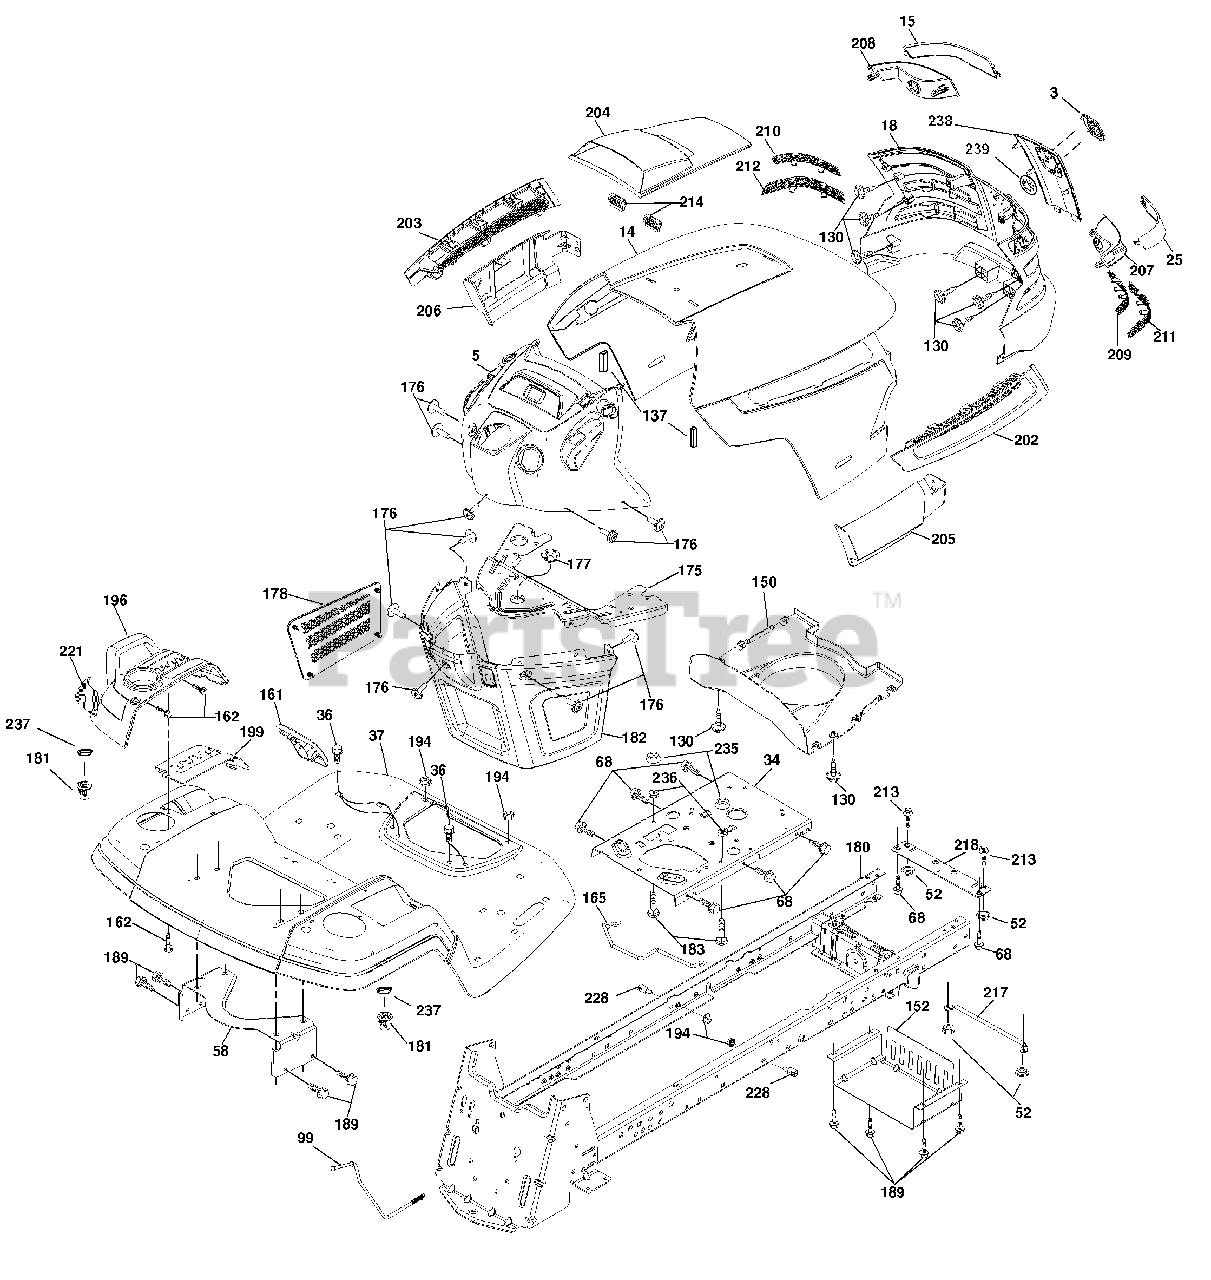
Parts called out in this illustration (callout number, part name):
3	Logo Husq
14	Hood
34	Plate Engine
36	Screw 5/16-18 x 3/4
37	Fender
52	Nut Lock 5/16-18
58	Bracket Fender
68	Screw 5/16-18 x 1/2
99	Rod Bypass Asm.
130	Screw 10 x 3/4 Single Lead Hex
137	Bumper Hood
150	Duct Heat Hood
152	Shield Browning/Debris
161	Console Fuel Window
162	Screw Hex Wsh Hi-Lo 1/4 x 1/2
165	Bracket Support Tank
175	Crossmember
176	Screw 10-24 x 5/8 Rnd Qdrx
177	Bushing Steering
178	Cargo Asm. Net
180	Chassis
181	Bushing Mtg. Fender Crgo.
182	Dash Lower
183	Bolt 5/16-18 x 1-1/4
189	Screw 5/16-18 x 3/4
194	Nut Lock Hex Flange 5/16-18
196	Console Asm. Deck Lift
199	Plate Deck Lift
202	Vent Side Hood RH
203	Vent Side Hood LH
204	Vent Asm Hood Top
205	Skirt Hood Side RH
206	Skirt Hood Side LH
209	Insert Hex Top RH
210	Insert Hex Top LH
211	Insert Hex Bottom RH
212	Insert Hex Bottom LH
213	Bolt Hex Hd 5/16-18 unc x 3/4
214	Clip Retainer
217	Rod Pivot
221	Reflector LH
228	Stud Fastner
235	Spacer Fender
236	Nut Lock 5/16-18 unc
